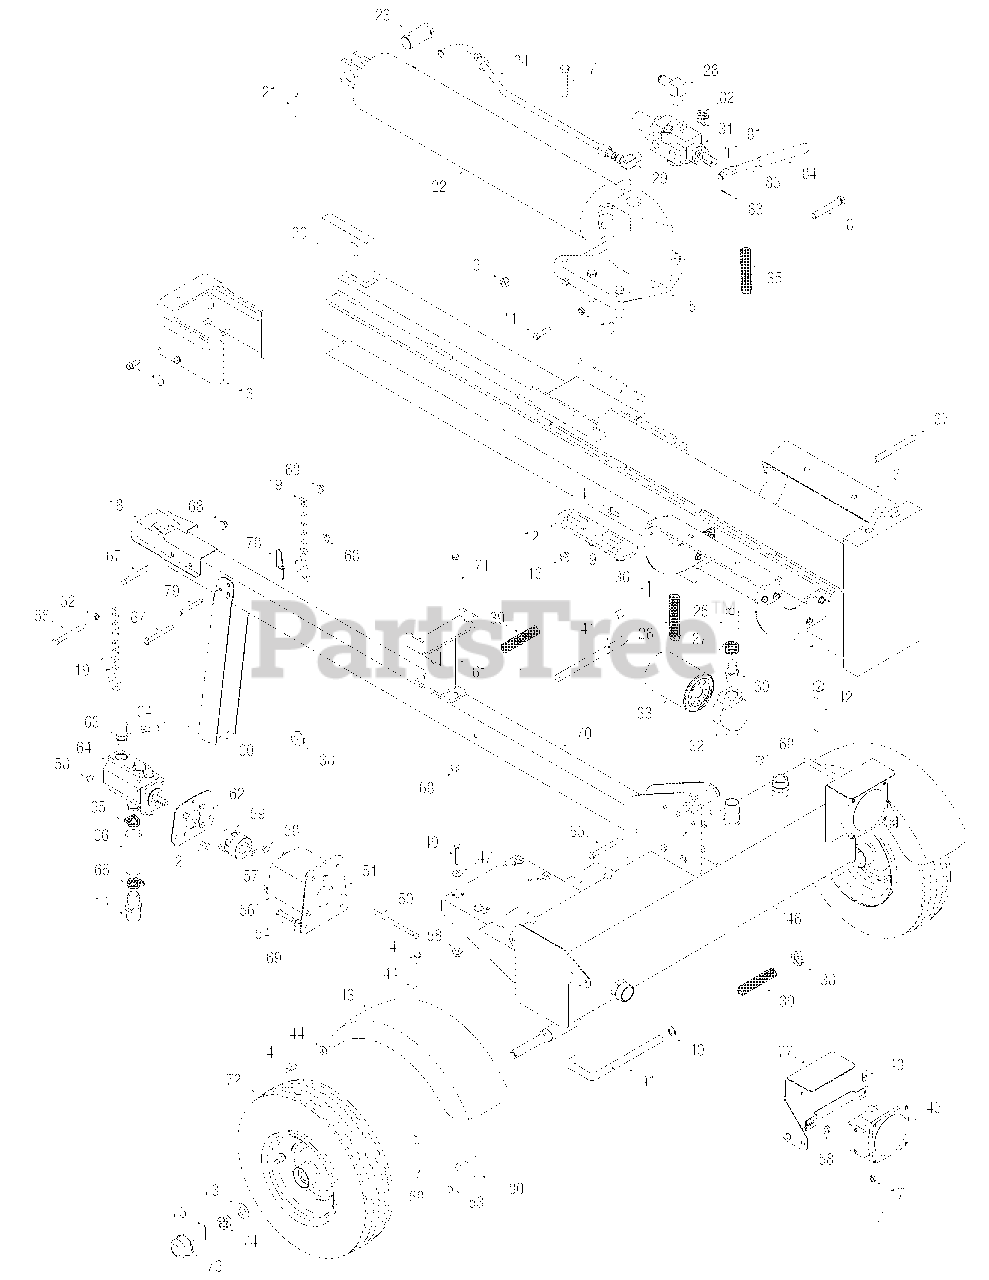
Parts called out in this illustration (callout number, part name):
2	Hex Screw, 5/16-18 x 1.00
4	TT Screw, 5/16-18 x .875
5	Wedge Assembly
6	Lock Nut 1/2-13
7	Hex Cap Screw 1/2-20 x 2.75
8	Hex Cap Screw 1/2-13 x 3.25
10	Hex Jam Nut 3/8-24
11	Hex Cap Screw 3/8-24 x 1.5
13	Hex Lock Nut, 1/2-20
14	Inlet Filter
15	Hex Washer Screw 3/8-16 x 1.0
17	Jam Nut, 3/8-16
18	Hitch Coupler, 2-inch
20	Beam Assembly
21	Cotter Pin
22	Kit Seal 5.0" for Best Metals cylinder 718-0313
22	Hydraulic Cylinder
22	Kit Seal 5.0" for XINGHUI cylinder 718-0313A
22	Kit Seal 5.0" for ENERGY cylinder 718-0313A
23	Clevis Pin
24	Hydraulic Tube
25	Return Hose 3/4" ID x 44"
26	Hose Guard
27	Hose Clamp 5/8"
28	Return Elbow
29	90 Degree Solid Male Adapter
30	3/4" Hose Adapter
31	Control Valve
32	Filter Housing
33	Oil Filter
34	High Pressure Hydraulic Hose
35	Hose Guard
36	Cotter Pin 1/8"
37	Hinge Pin 1/2 x 4.8" Lg.
38	Push Cap
39	Compression Spring 4"
40	Flat Washer .635 ID x .93 OD
41	Locking Rod
42	Vented Dipstick
43	Fender
44	Flat Washer, .343 x .880 x .062
45	Tail Light Assembly
45	Tail Light - RH
45	Tail Light - LH
45	Wire Harness
46	Frame Assembly 7.0 Gal
47	Bell Washer, 340 x .872 x .060
48	Nut 1/4-20
49	Hex Cap Screw 5/16-18 x 1.75
50	Hex Cap Screw 5/16-18 x 4.75
52	Flat Washer, .375 x .738 x .063
53	Screw, TT, 5/16-18 x 1.00
54	Hex Cap Screw, 5/16-24 x .75
55	Hex Cap Screw 3/8-16 x 3.50
56	Coupling Shield
57	Key, 3/16 x .75
58	Hex Flange Lock Nut, 5/16-18
59	Flex Coupling
63	Adapter, 3/4-16
64	Pump
65	Hose Clamp
66	Suction Hose
67	Hex Cap Screw 3/8-16 x 3.0
68	Flange Lock Nut, 3/8-16
69	Lock Washer, 5/16
71	Hex Cap Screw 3/8-16 x 4.0
72	Wheel Assembly
73	Flat Washer .76" ID x 1.5" OD
74	Slotted Nut 3/4-16
75	Cotter Pin 5/32" x 1-1/4"
76	Hub Cap
79	Pin, Clevis
81	Clevis Pin
82	Valve Handle Link
83	Cotter Pin
85	Hydraulic Valve Control
